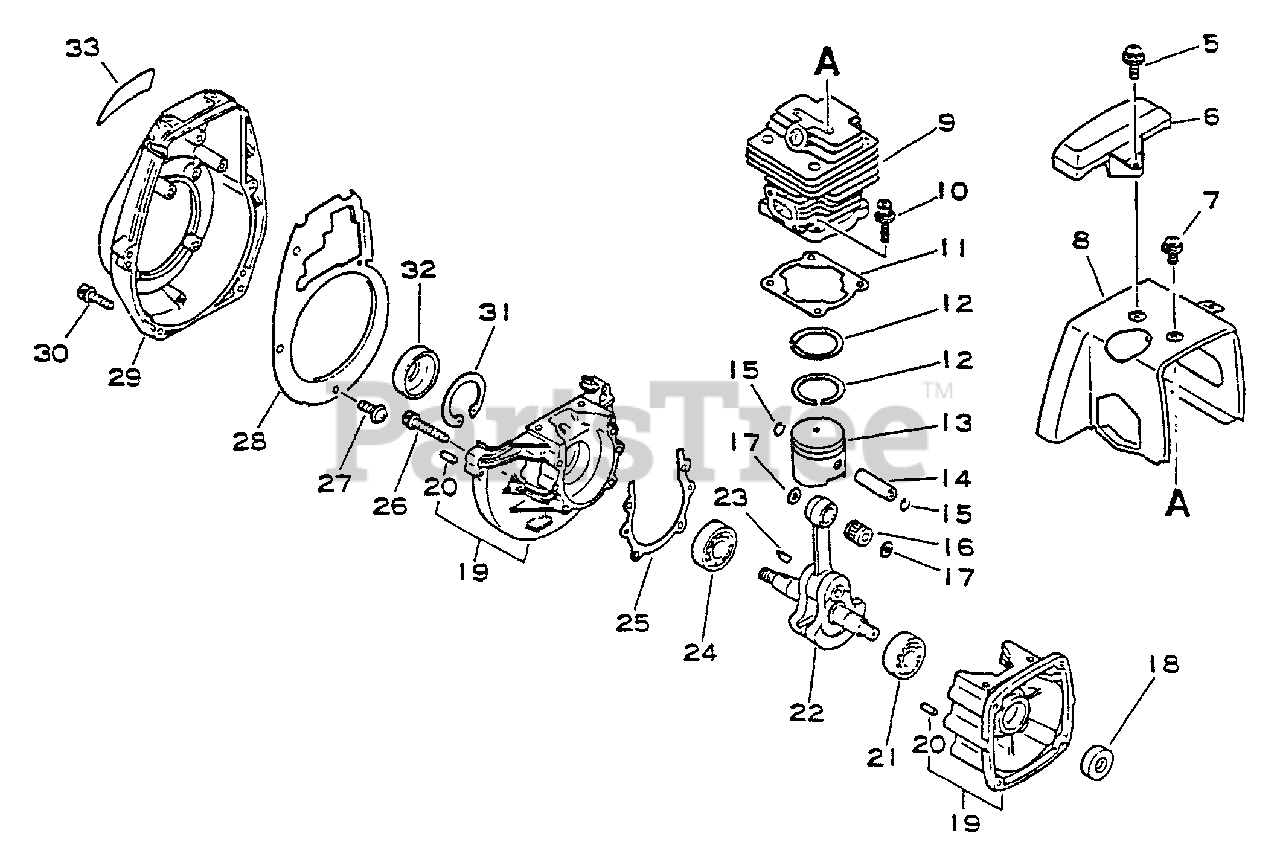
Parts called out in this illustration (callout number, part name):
5	SCREW 5×14
6	GUARD, TOP
7	SCREW 5×10
8	COVER, ENGINE
9	CYLINDER
10	BOLT 5×20
11	GASKET, CYLINDER
12	RING, PISTON
13	RING, PISTON
14	PIN, PISTON
15	RING, SNAP 8
16	BEARING, NEEDLE
17	WASHER, THRUST
18	SEAL, OIL 12
19	CRANKCASE KIT
20	PIN, LOCATING 5×10
21	BEARING, BALL - 6201 C3
22	CRANKSHAFT ASSY
23	KEY, WOODRUFF
24	BEARING, BALL 6202
25	GASKET, CRANKCASE
26	BOLT 5×30
27	SCREW 4×10
28	GUIDE, AIR
29	COVER, FAN
30	BOLT 5×25
31	RING, SNAP 35
32	SEAL, OIL 18
33	LABEL - MODEL
